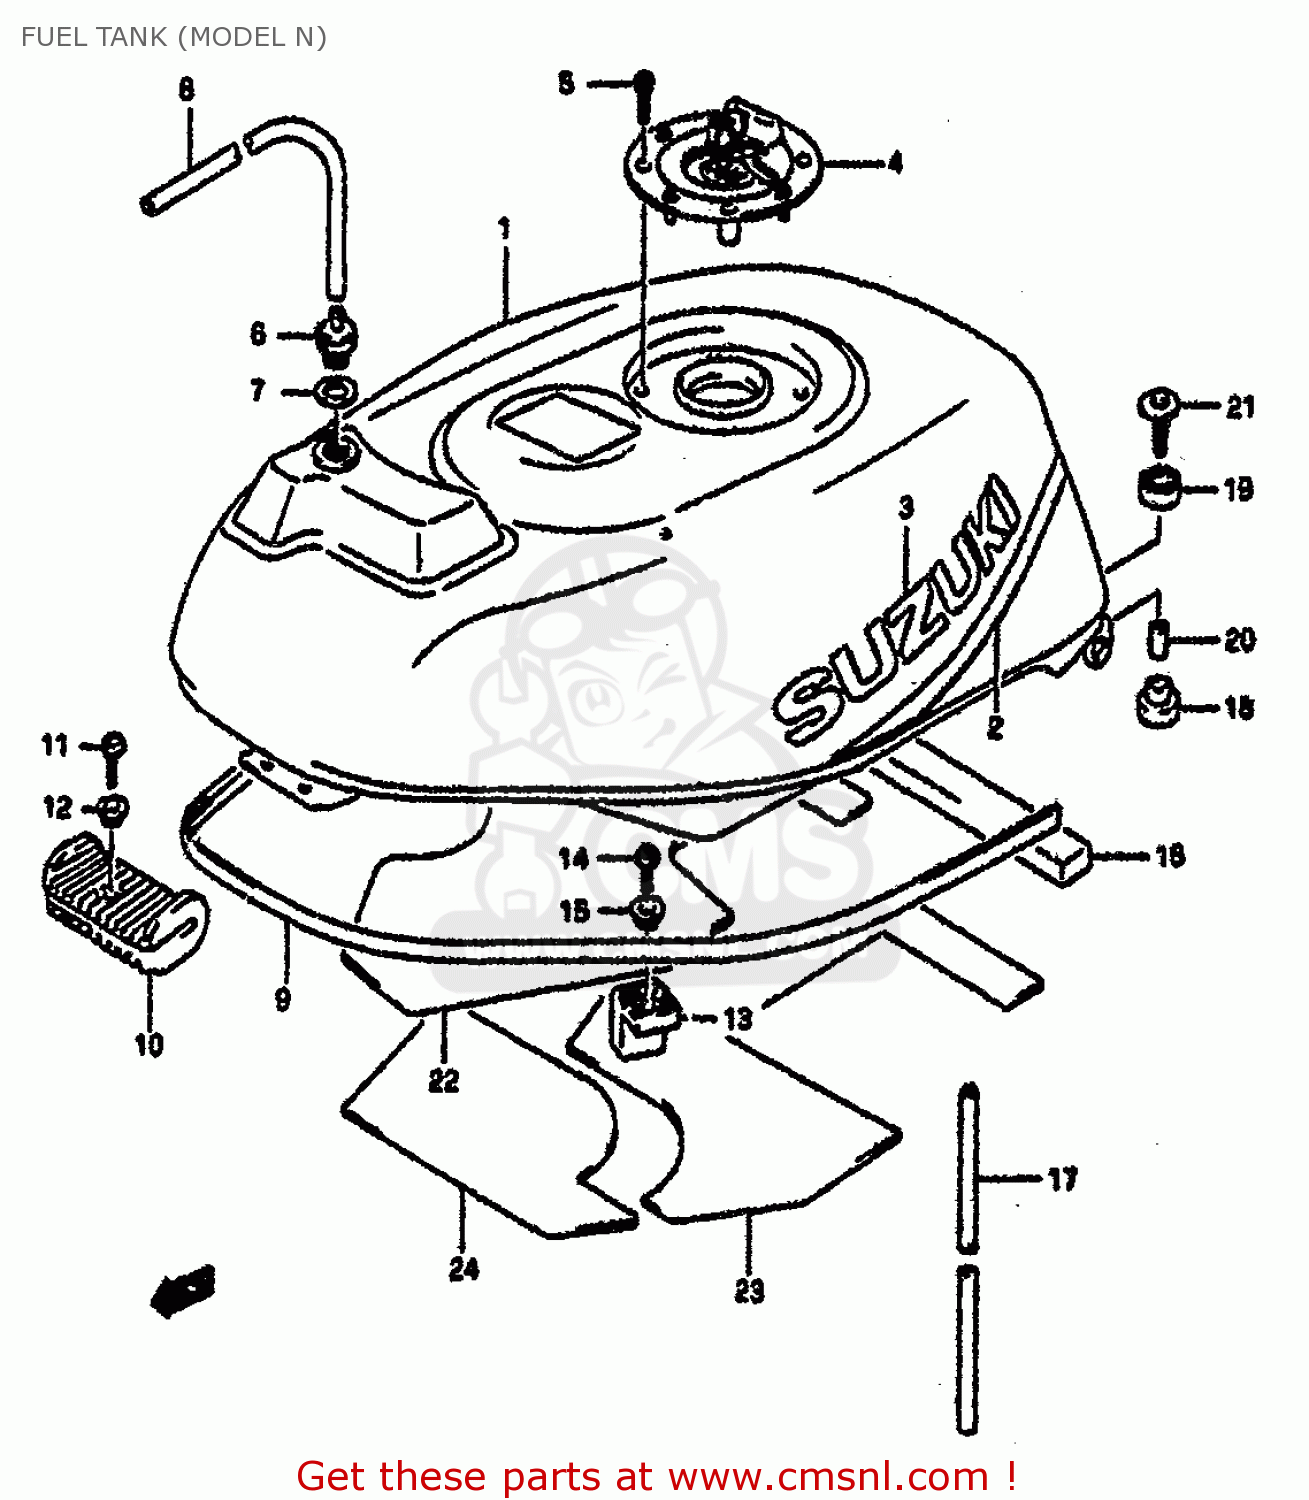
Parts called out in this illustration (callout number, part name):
1	TANK ASSY, FUEL
2	TAPE,FUEL TANK
3	EMBLEM,FUEL TANK
4	CAP SET,FUEL TANK
5	BOLT(5X20)
6	PLUG,FUEL TANK BREATHER
7	GASKET(12.5X20X2.5) (NAS)
8	HOSE(5X8.2X600)
9	MOLDING,FUEL TANK
10	CUSHION,FUEL TANK FR
11	SCREW 5X10
12	WASHER
13	CUSHION,FUEL TANK SIDE
14	SCREW
15	WASHER
16	CUSHION, AIR SEAL
17	HOSE
18	CUSHION
19	CUSHION
20	SPACER
21	BOLT(6X35)
22	SHIELD,FUEL TANK HEAT
23	HEAT SHIELD,FUEL TANK IN
24	HEAT SHIELD,FUEL TANK IN
28	SHIELD,FUEL TANK HEAT
29	HEAT SHIELD,FUEL TANK IN
30	HEAT SHIELD,FUEL TANK IN
